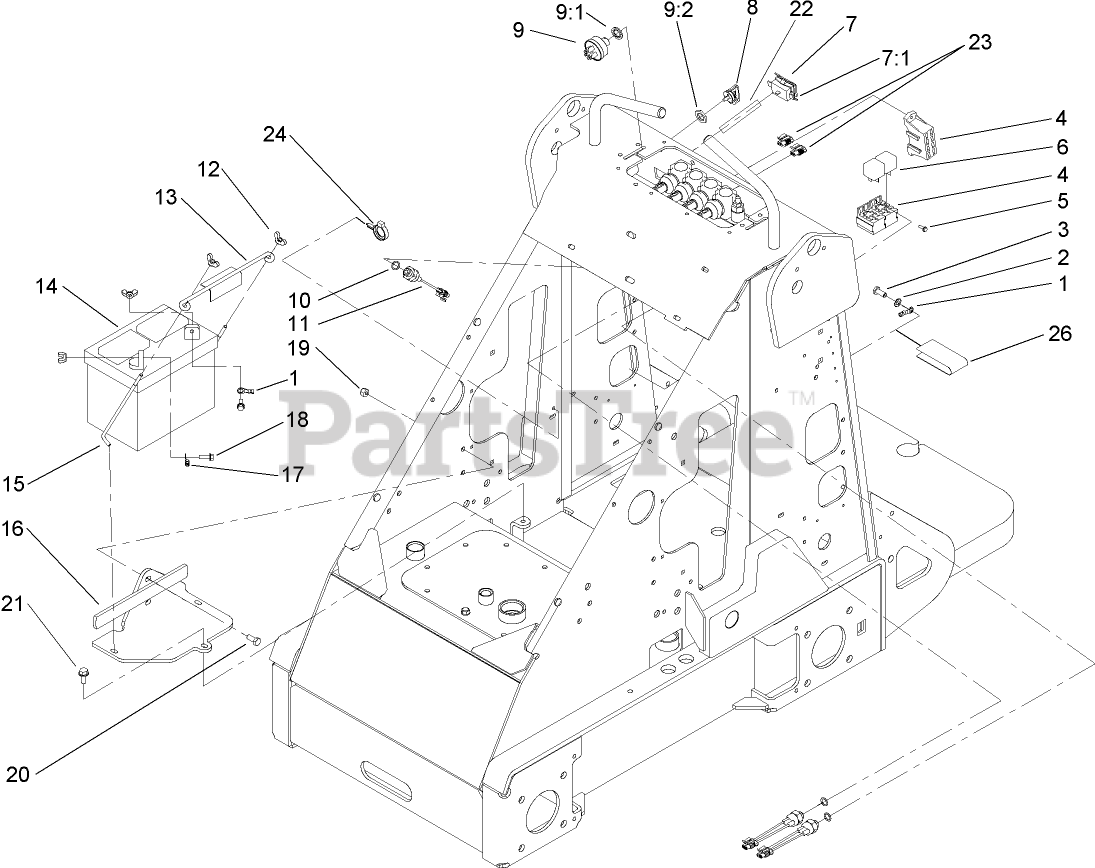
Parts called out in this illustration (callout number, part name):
1	CABLE-BATTERY, NEGATIVE
2	WASHER-LOCK
3	SCREW-HH
4	HARNESS-WIRE
5	SCREW-HWHTF
6	RELAY
7	HOURMETER-INDUCTIVE
7:1	CLIP-MOUNTING
8	KEY-IGNITION
9	IGNITION SWITCH ASM
9:1	WASHER-LOCK
10	O-RING
11	SWITCH-BALL
12	NUT-WING
13	HOLDDOWN-BATTERY
14	BATTERY-DRY
15	RETAINER-BATTERY
16	BATTERY MOUNT ASM
17	CABLE-POSITIVE
18	SCREW-HHF
19	NUT-LOCK, NI
20	SCREW-HH
21	SCREW-HWHTF
22	WIRE-HOURMETER
23	Connector-Female
24	CLAMP-HOSE
26	DECAL-INSTRUCTIONS, CHARGING
